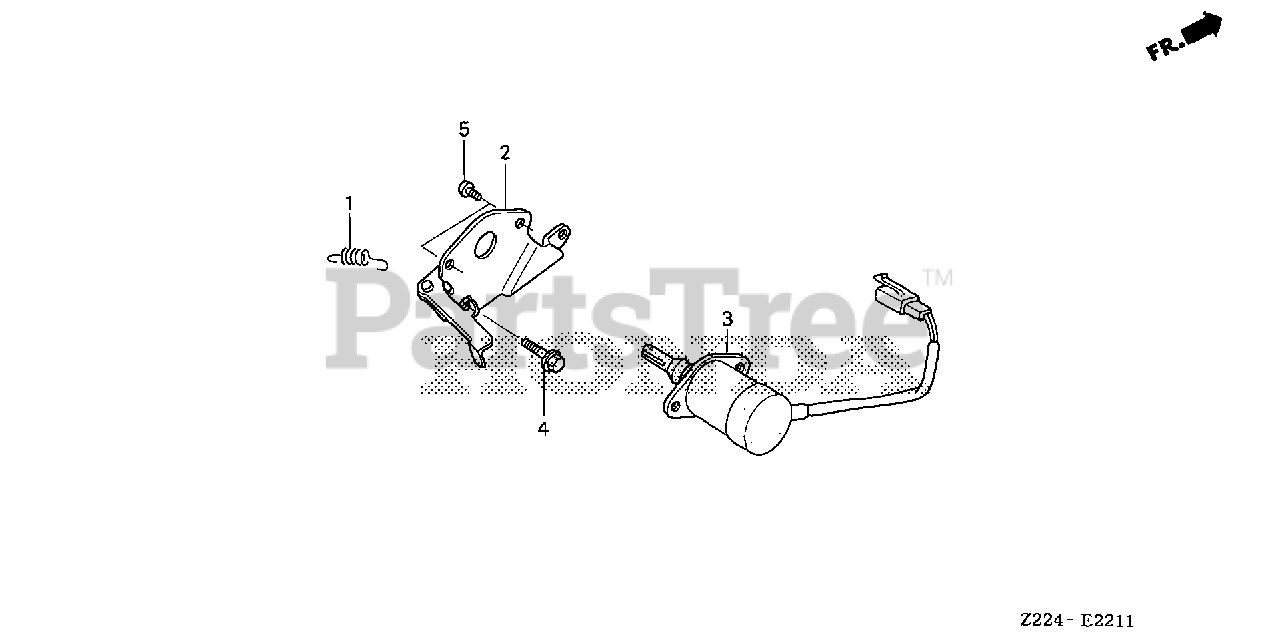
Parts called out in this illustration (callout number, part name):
1	SPRING, CHOKE RETURN
2	LEVER, THROTTLE
3	SOLENOID ASSY.
4	BOLT, FLANGE (6X12) (CT200)
5	SCREW, PAN (5X8)
